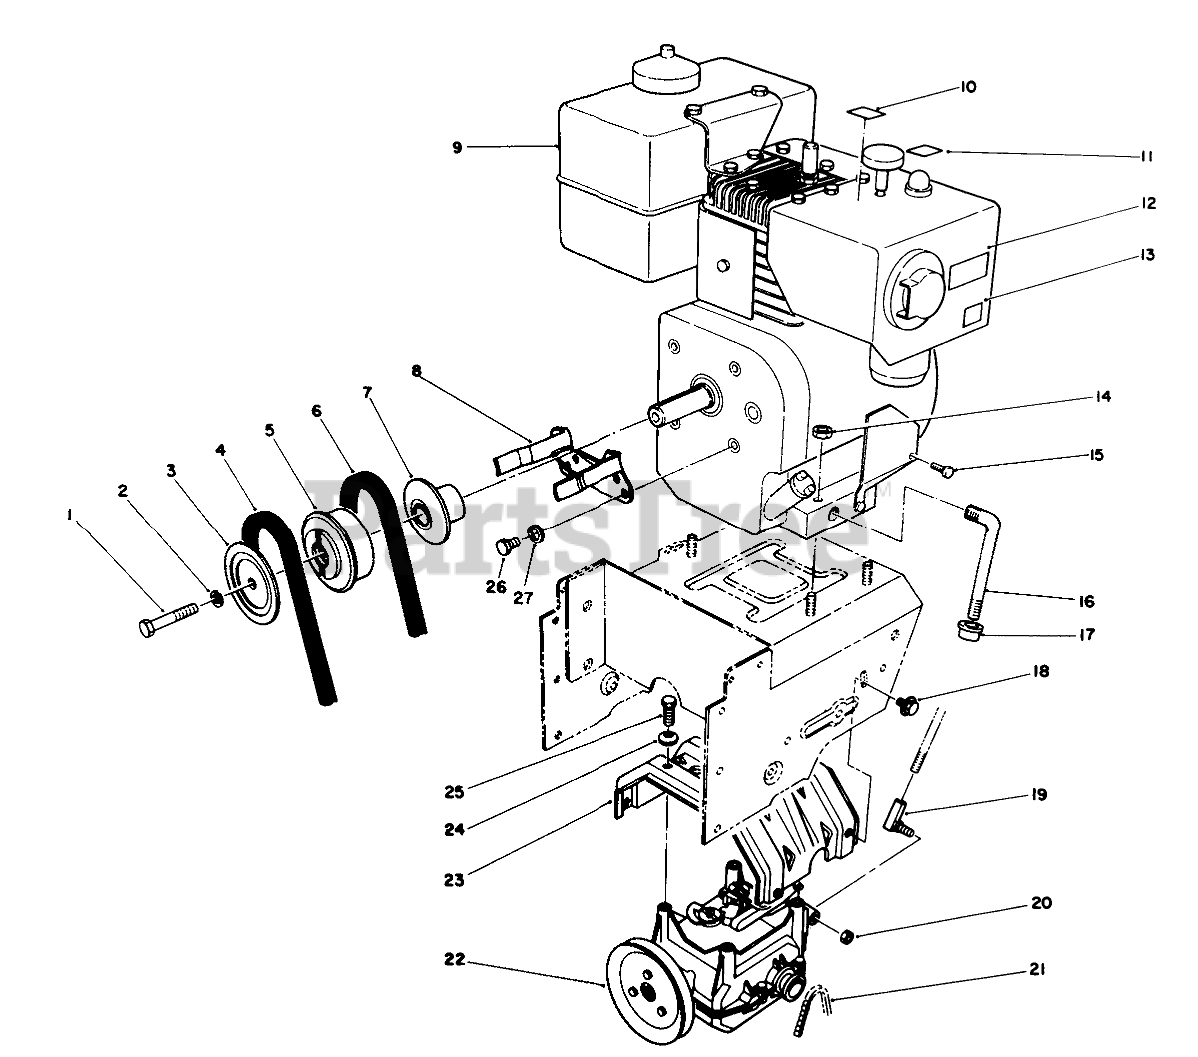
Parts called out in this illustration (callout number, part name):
1	SCREW-HH
2	WASHER-LOCK
3	SHEAVE-HALF, IMPELLER
4	V-BELT, IMPELLER
5	PULLEY-ENGINE, CENTER
6	V-BELT, TRACTION
7	SHEAVE-HALF, TRACTION
8	Guide-Belt
10	DECAL - THROTTLE, INT'L
11	DECAL - PRIMER, INT'L
12	DECAL-WARNING, HOT SURFACE
13	DECAL - CHOKE
14	NUT-HF
15	SCREW-HH
16	8 HP DRAIN TUBE
17	CAP-PIPE
18	SCREW-HHF
19	JOINT-BALL
20	NUT-LOCK, NI
21	CHAIN
22	TRACTION GEARCASE ASM
23	Frame-Transmission
24	WASHER-SPRING
25	SCREW-HWHTF
26	SCREW-HH
27	WASHER-LOCK
